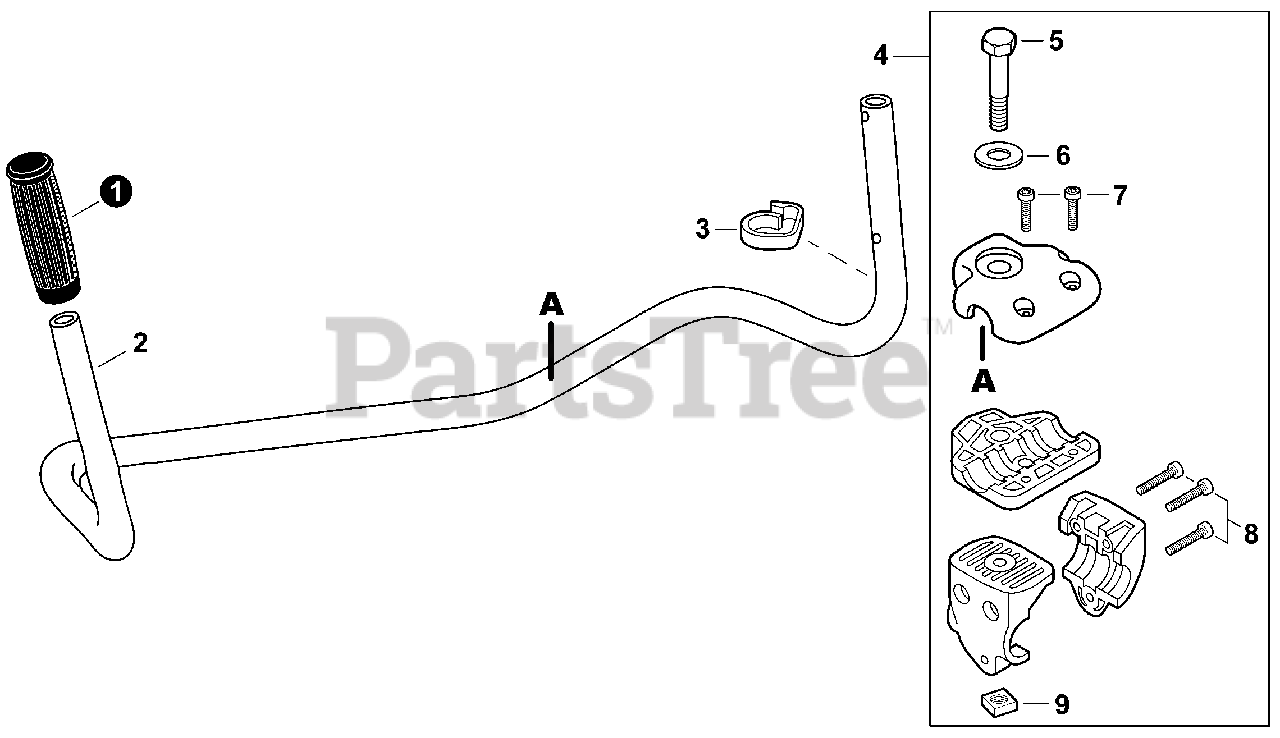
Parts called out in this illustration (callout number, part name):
1	GRIP, HANDLE
2	U-HANDLE
4	BRACKET KIT, U-HANDLE
5	BOLT 8×55
6	WASHER 8
7	BOLT, TORX 5×20
8	BOLT, TORX 5×25
9	NUT 8×1.25
